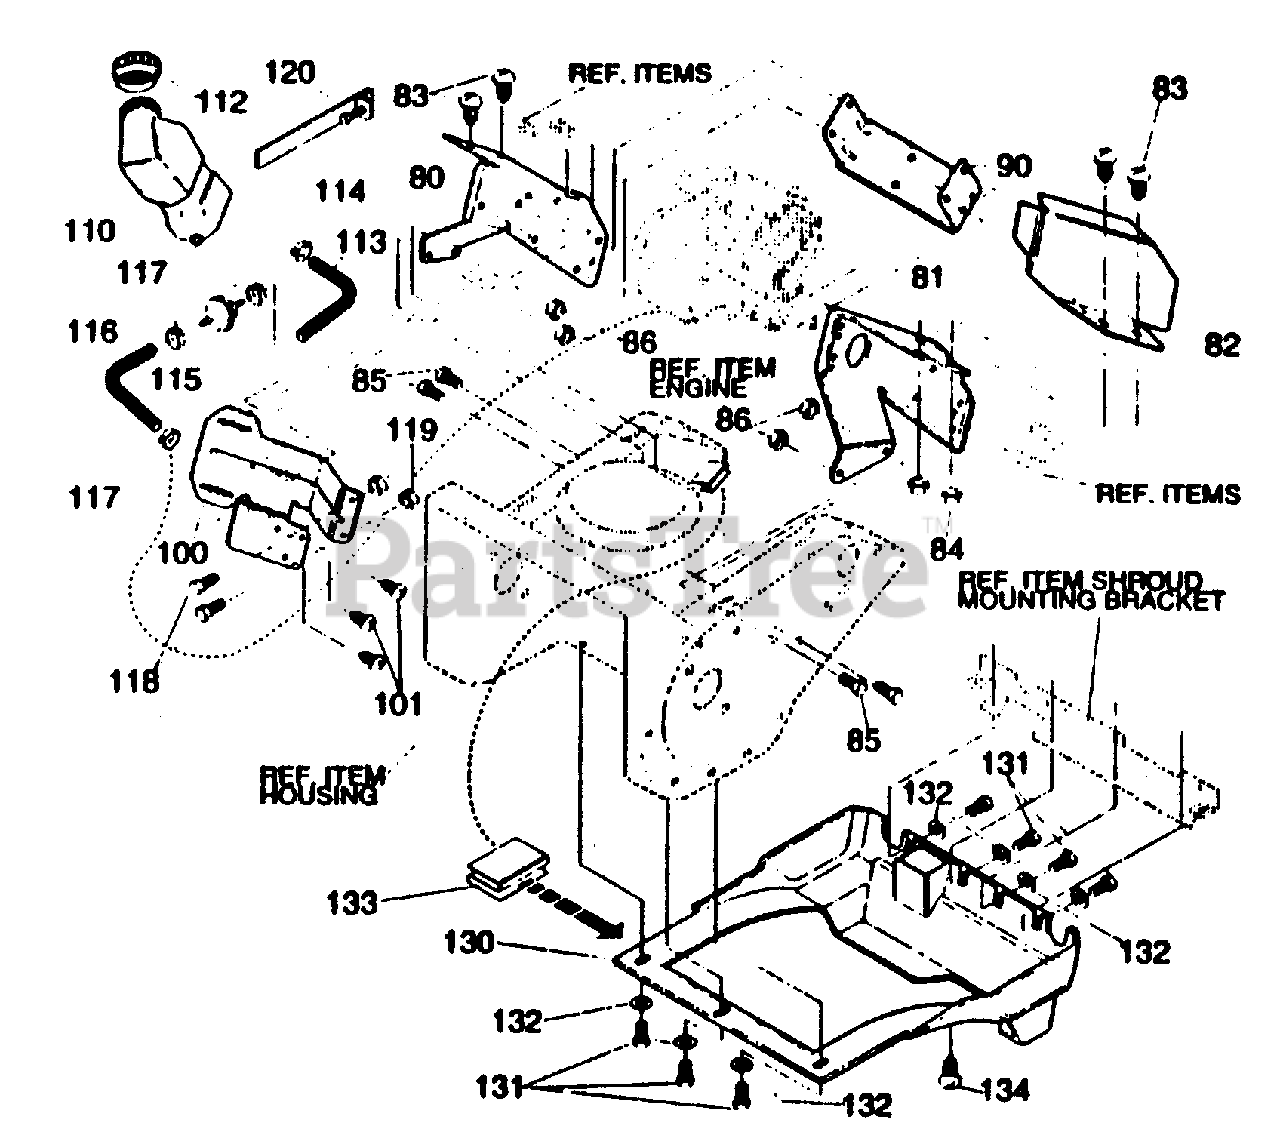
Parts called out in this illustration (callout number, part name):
80	PLATE, REAR RH
81	PLATE, REAR LH
82	SHIELD, ENGINE HEAT
83	SCREW, 1/4-20X .63
84	NUT, 1/4-20 WDFL
85	SCREW, 5/16-18X .50
86	NUT, 5/15-18
90	SUPPORT, FRAME
100	BRACKET, GAS TANK
101	SCREW, #10-24X .63
110	TANK, FUEL
113	TUBING, GAS LINE
114	CLAMP, HOSE
115	FILTER, IN-LINE
116	TUBING, GAS LINE
117	CLAMP, HOSE
118	SCREW, 10-24X .50
119	NUT, #10-24
120	CLAMP, WORM
130	COVER, BOTTOM
131	SCREW, #10-24X .63
132	WASHER, FLAT .203X .56X.04o
133	CLIP, "S" TINNERMAN
134	SCREW, 10-16X .50
